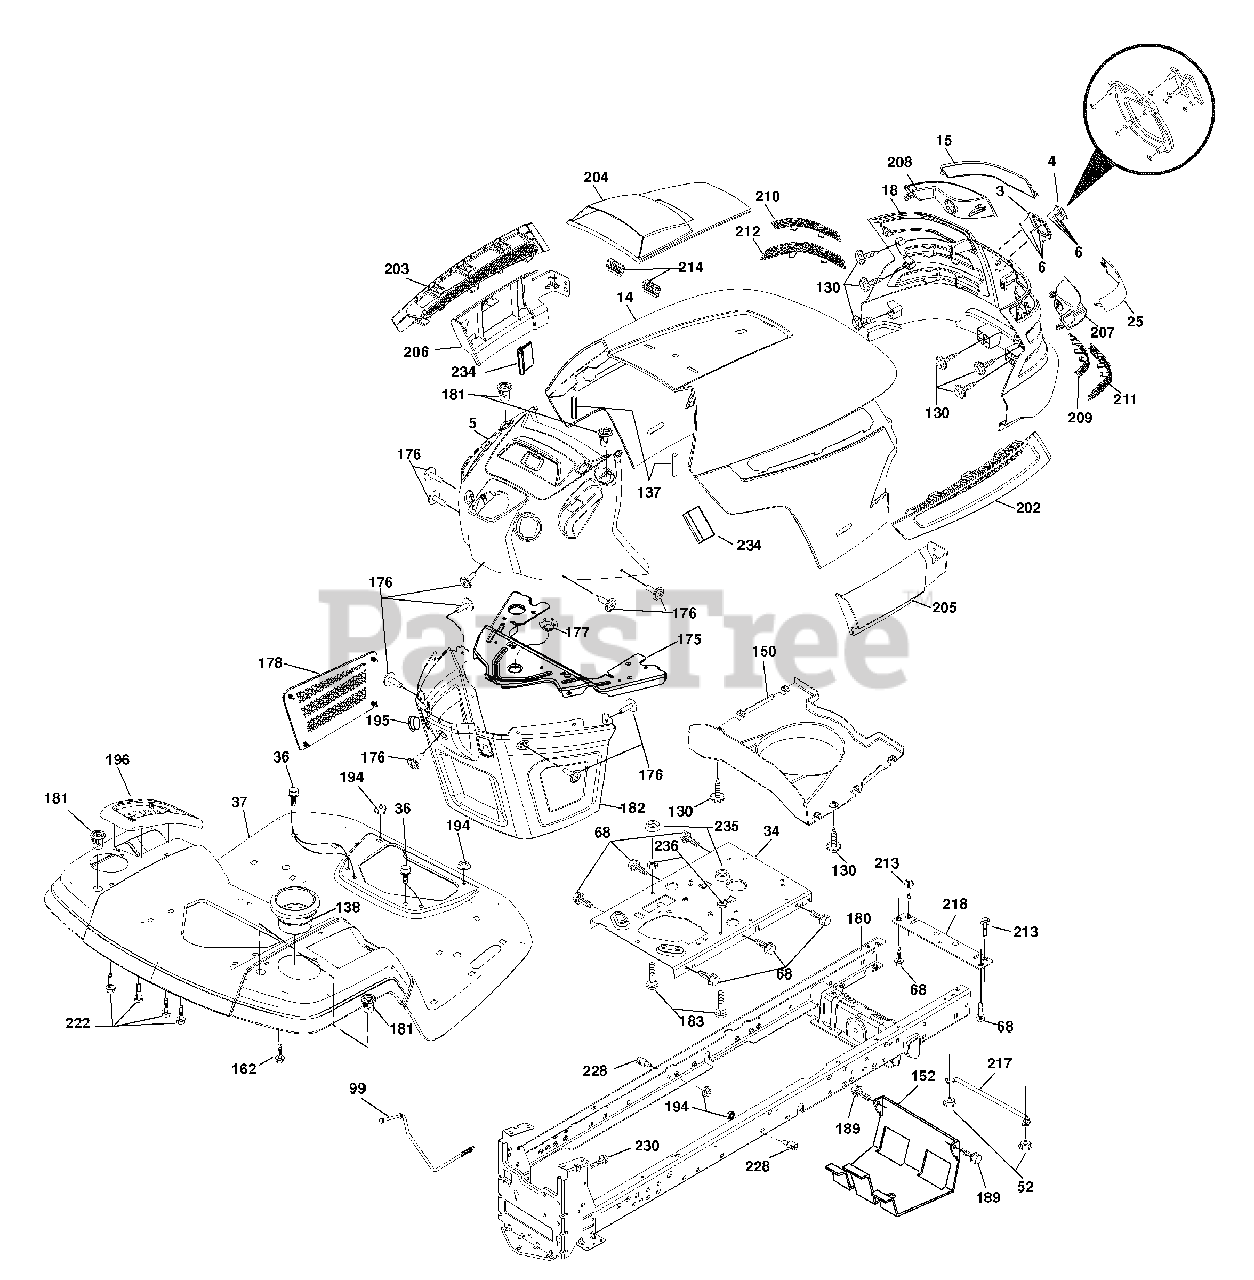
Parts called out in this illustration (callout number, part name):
3	Logo Crown
4	Logo
14	Hood
18	Grille/Lens Asm.
34	Plate Engine
36	Screw 5/16-18 x 3/4
37	Fender
52	Nut Lock 5/16-18
68	Screw Thdrol 5/16-18 x 1/2
99	Rod Asm Bypass
130	Screw 10 x 3/4 Single Lead-Hex
137	Bumper Dash
138	Cupholder
152	Shield Browning
175	Crossmember
176	Screw 10-24 x 5/8
177	Bushing Steering
178	Cargo Net Asm.
180	Chassis
181	Bushing Mtg. Fender Crgo
182	Dash Lower
183	Bolt Fin Hex 5/16-18 unc x 1-1/4
189	Screw 5/16-18 x 3/4
194	Nut Lock Hex Flange 5/16-18
195	Plug Hole Dash Lower
196	Console Asm. Deck Lift
202	Vent Side Hood RH
203	Vent Side Hood LH
204	Vent Top Hood
205	Skirt Hood Side RH
206	Skirt Hood Side LH
209	Insert Hex Top RH
210	Insert Hex Top Lh
211	Insert Hex Bottom RH
212	Insert Hex Bottom LH
213	Bolt 5/16-18 x 3/4
214	Clip Retainer Tinner
217	Rod Pivot
218	X-Piece Hood Stop
222	Screw Thdrol 1/4-20 x 5/8
228	Stud Fastner
230	Bolt Shoulder 5/16-18
234	Bumper Hood
235	Spacer Fender
236	Nut Lock 5/16-18 UNC
